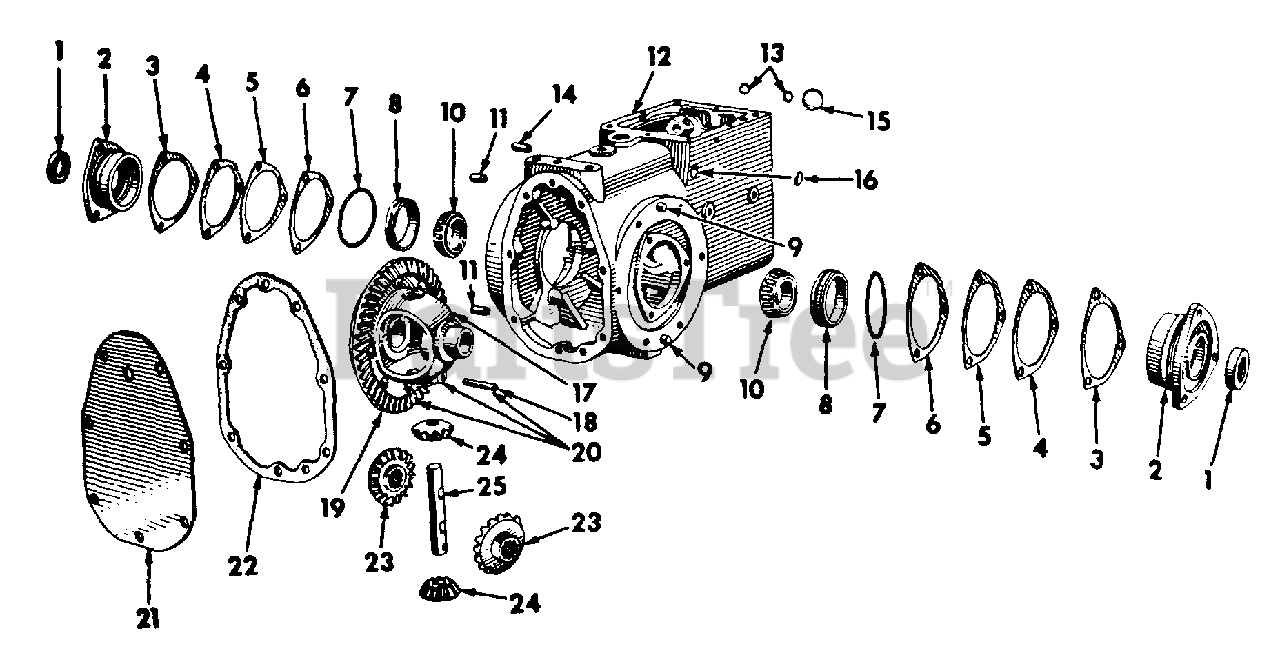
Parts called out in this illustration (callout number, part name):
1	SEAL BRG RETAINER OIL
2	RETAINER ASSY, BRG
3	SHIM, BEARING RETAINER .004
4	SHIM, BEARING RETAINER .007
5	SHIM, BEARING RETAINER .0149
6	SHIM, BEARING RETAINER .0299
7	O-RING, 3-1/8 X 3-3/8 X 1/8
8	BEARING, CUP
9	PIN, CASE TO REAR RH AXLE HOUSING DOWEL
10	BEARING ASSY, CONE
11	PIN, CASE TO REAR LH AXLE HOUSING DOWEL
12	CASE ASSY, TRANSMISSION
13	PLUG, 9/16 EXPANSION - GEAR SHIFTER ROD HOLE
14	BUSHING, ACTUATING TOGGLE
15	PLUG, 1-3/16 EXPANSION REVERSE IDLER GEAR SHAFT
16	PLUG, 11/16 EXPANSION PTO SHIFTER SHAFT BEARING
17	CASE, DIFFERENTIAL
18	PIN, PINION SHAFT LOCK
19	GEAR, DRIVE - 46T
20	CASE W/DRIVE GEAR ASSY, DIFFERENTIAL
21	PLATE ASSY, REAR COVER
22	GASKET, TRANSMISSION CASE REAR COVER PLATE
25	SHAFT, PINION
